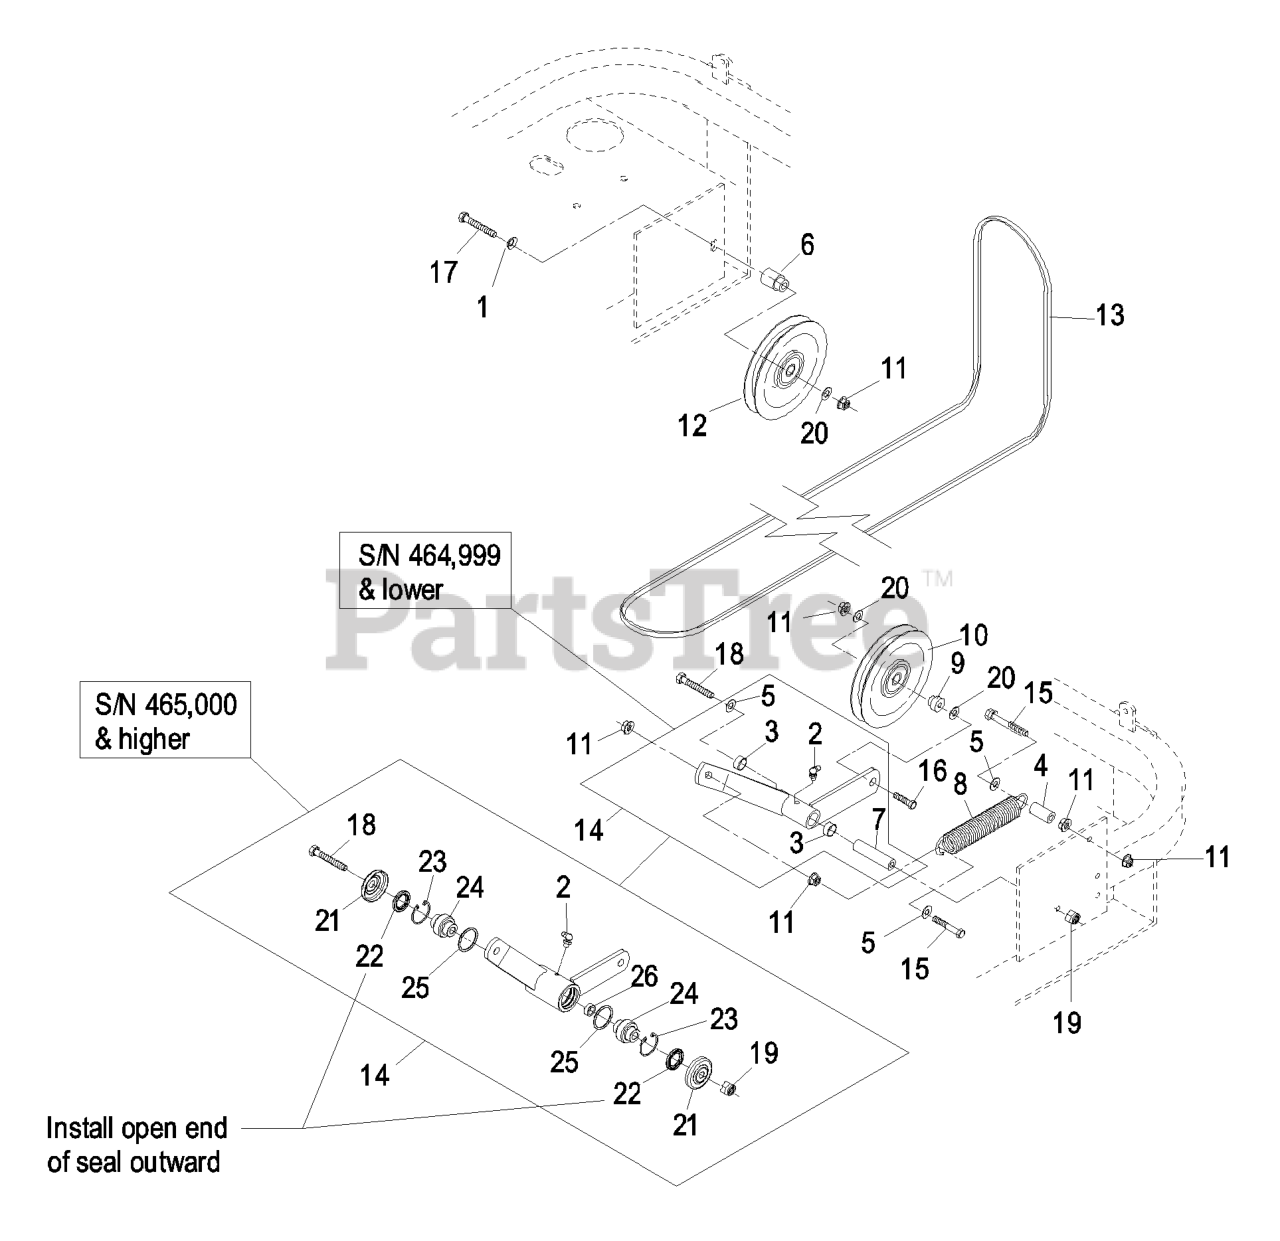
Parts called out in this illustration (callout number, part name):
1	WASHER-BELLEVILLE
2	FITTING-GREASE, 90 DEG
3	SLEEVE-BEARING
5	WASHER-FLAT
6	BUSHING-IDLER
7	BUSHING-PIVOT, IDLER
8	SPRING-EXTENSION
9	BUSHING-IDLER
10	PULLEY-IDLER
11	NUT-HHF, WHIZ
12	PULLEY-IDLER
13	BELT,B 116.1"
14	KIT,MULE IDLER LZ
15	SCREW-HH
16	SCREW-HH
17	SCREW-HH
18	SCREW-HH
19	NUT-LOCK, NI
20	WASHER-FLAT
21	GUARD-TOP
22	SEAL-LIP, SINGLE
23	RING-SNAP
24	BEARING-SPHERICAL
25	O-RING
26	SPACER
